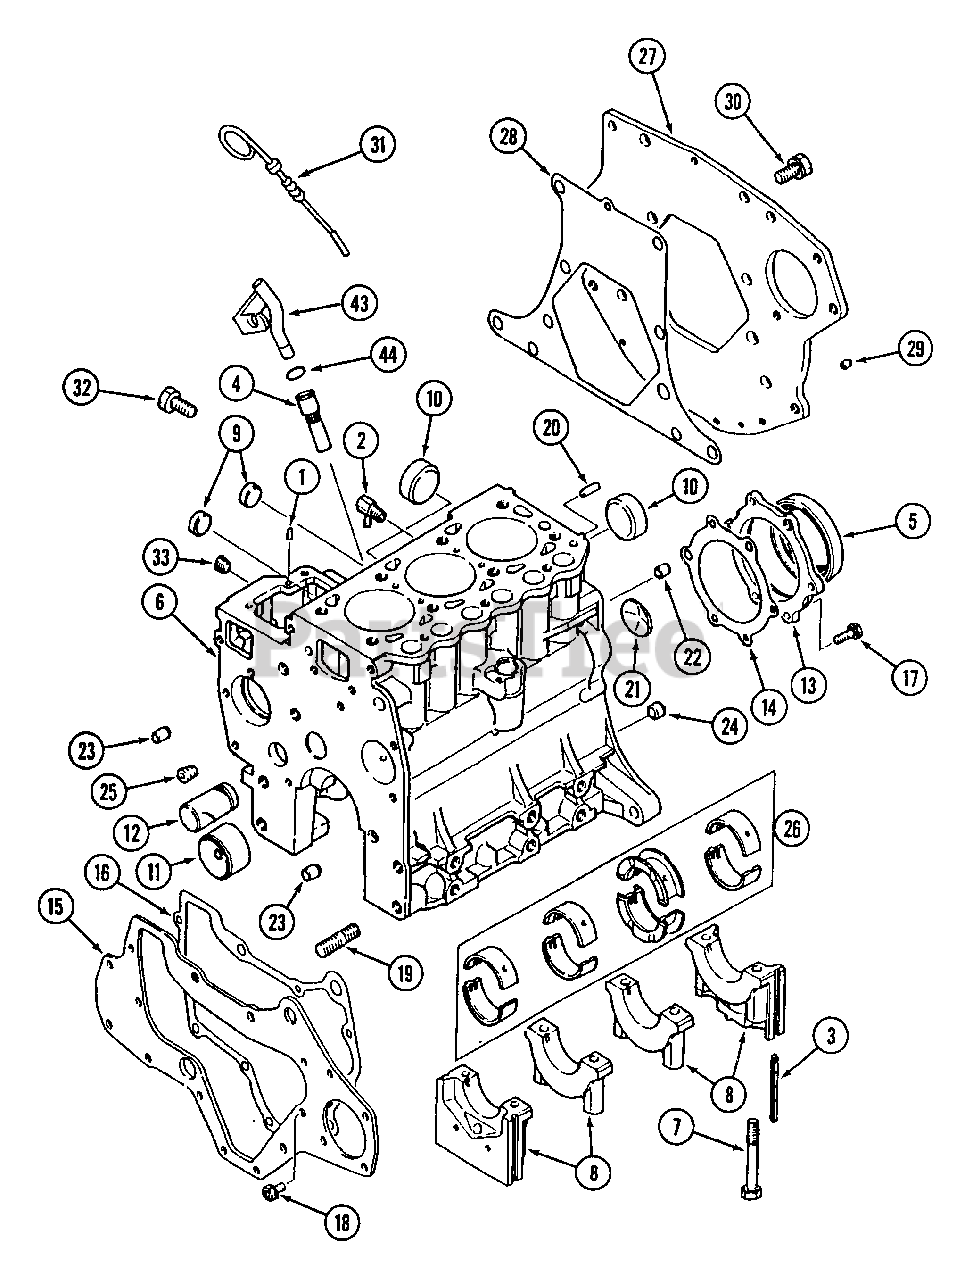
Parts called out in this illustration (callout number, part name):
2	Joint, Water Drain
4	Retainer, Oil Level Gauge
6	Cylinder, Block, Sub Assembly
7	Bolt, Bearing Cap
8	Bearing, Cap Ass'y.
9	Cap, Sealing
10	Cap, Sealing
11	Bushing, Camshaft
12	Shaft, Idler
13	Case, Oil Seal
14	Gasket, Oil Seal
15	Plate Front
16	Gasket, Front Plate
17	Bolt, w/Washer
18	Bolt, w/Washer
21	Plug, Expansion
22	Bushing, Knock
23	Bushing, Knock
24	Bushing, Knock
25	Plug, Taper
26	Bearing Set STD.
26	Bearing Set 0.25 US
26	Bearing Set 0.50 US
26	Bearing Set 0.75 US
28	Gasket Rear Plate
30	Bolt, w/Washer
31	Gauge, Oil Level
33	Plug, Taper
43	Guide, Oil Level Gauge
44	O-Ring
